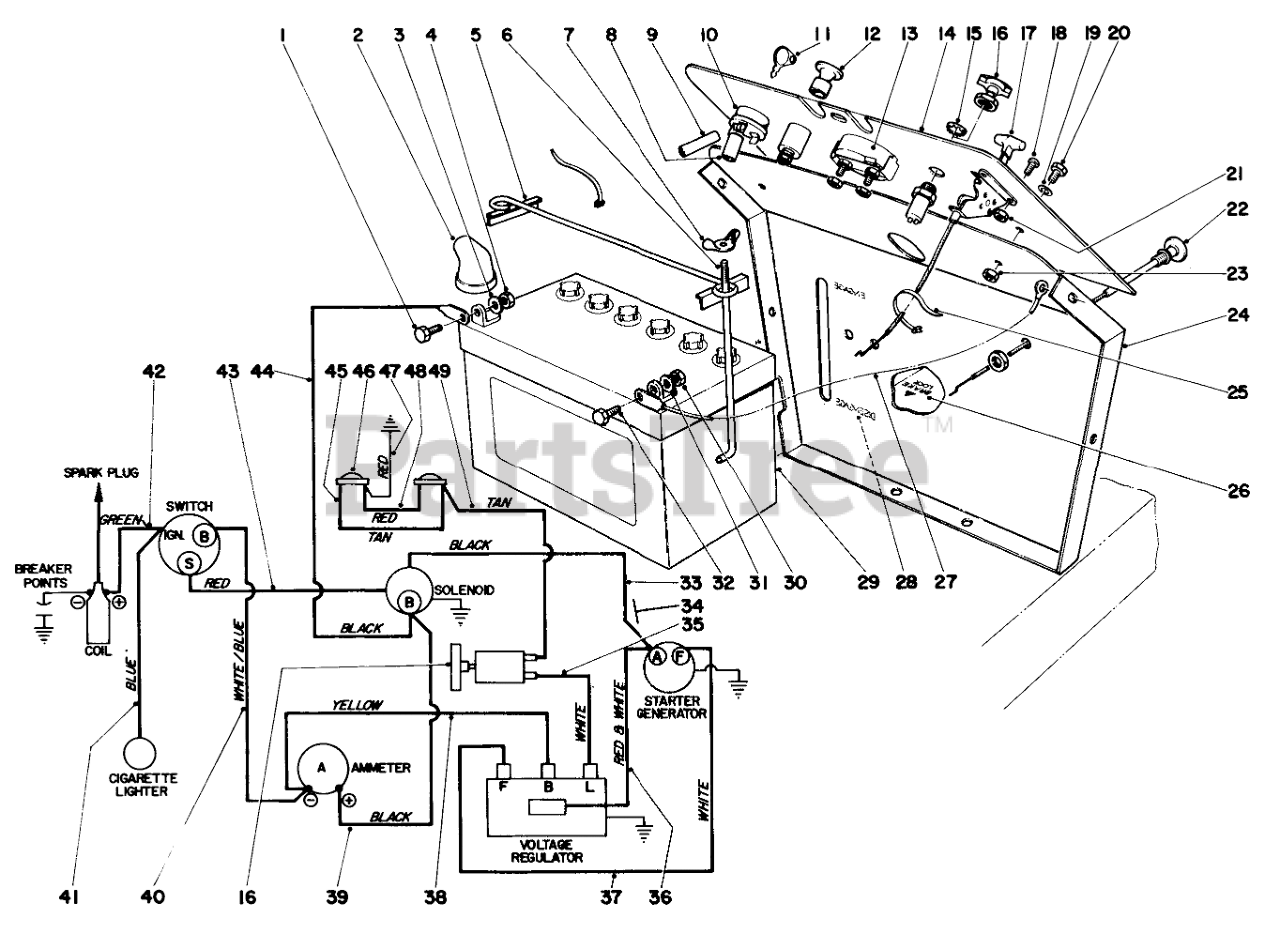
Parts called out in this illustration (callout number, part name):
1	SCREW-HH
2	Battery Boot
3	Washer
4	NUT-HEX
5	Battery Clamp
6	BATTERY BOLT
7	NUT-WING
8	Insulator
9	Insulator
10	Starter Switch
11	Key
12	Cigarette Lighter Assy.
13	Ammeter
14	Dash Panel
15	Plug Button 950
16	Light Switch
17	Throttle Control
18	Machine Screw
19	Washer
20	SCREW-HH
21	NUT-KEPS
22	Choke Control
24	Rear Hood Support
25	Cable Tie
26	Decal Brake
28	Decal Engage & Disengage
29	Battery
30	NUT-HEX
31	Washer
32	SCREW-HH
34	Wiring Harness
35	Wire 960
45	Wire 960
46	HEAD LAMP
47	Wire 960
48	Wire 960
49	Wire 960
